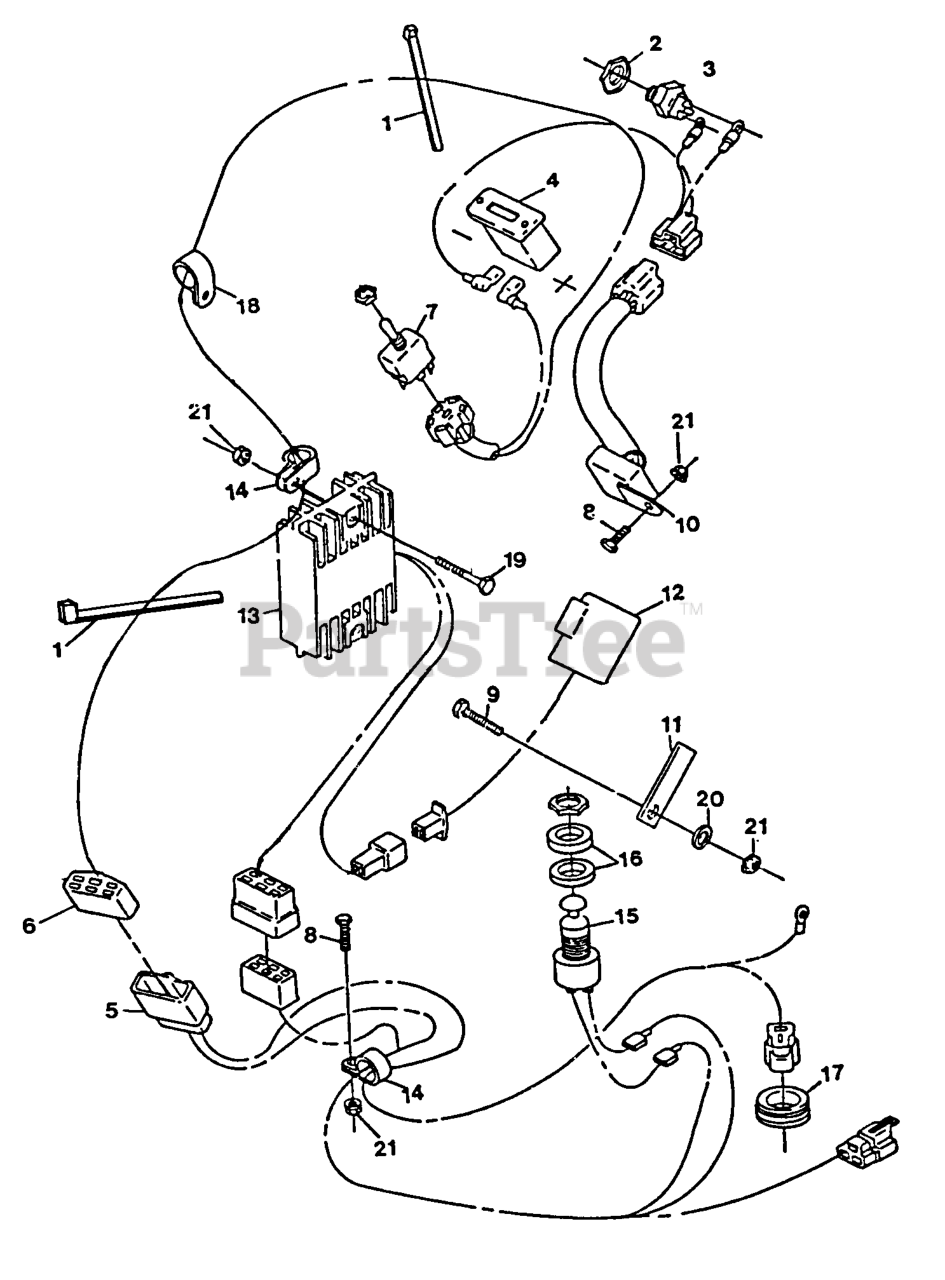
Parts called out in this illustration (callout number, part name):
1	TIE-PLASTIC
3	SWITCH,OPERATOR CNTRL
4	METER-HOUR
7	SWITCH,W/TERM CLIPPD
14	CLIP-LOOM
15	SWITCH,PUSH BUTTON
17	GROMMET
18	CLIP-LOOM
